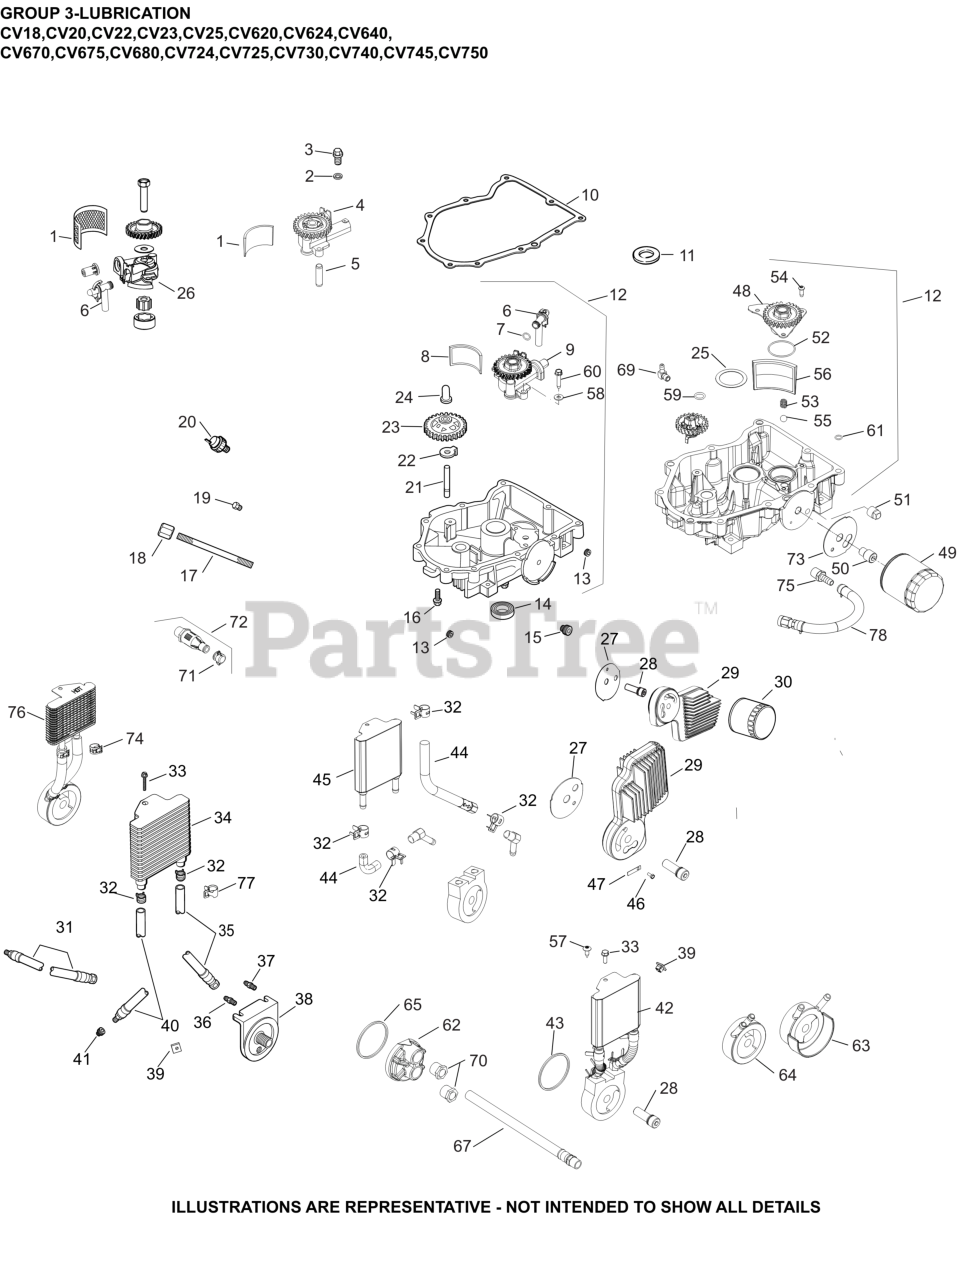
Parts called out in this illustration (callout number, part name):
10	GASKET, OIL PAN
12	KIT, OIL PAN ASSEMBLY
12	PAN, ASSEMBLY OIL (SERVICE)
13	PLUG, PIPE CTSK 3/8"
16	SCREW, FLG M8X1.25X45
19	PLUG, HD PIPE 3/8"
20	SENSOR, OIL PSI
21	SHAFT, GOVERNOR GEAR
22	TAB, LOCKING
23	KIT, GOVERNOR GEAR W/PIN
24	PIN, GOVERNOR REGULATING
28	NIPPLE, OIL FILTER - (#2413608S)
33	SCREW, TAP M6X1.7X18
39	NUT, PLASTIC - BLACK
43	O-RING, OIL COOLER
44	KIT, HOSE 140MM
48	PUMP, OIL ASSEMBLY
49	OIL FILTER
52	O-RING (1.78" DIA)
53	SPRING, COMPRESSION
54	SCREW, BUTTON HEAD
55	PRESSURE RELIEF BALL
56	SCREEN, OIL
60	SCREW, HEX FLANGE
64	ADAPTER, OIL FILTER (CV EFI)
74	CLAMP, HOSE LOW PROFILE
76	COOLER, OIL & DIVERTER ASSEMBLY
